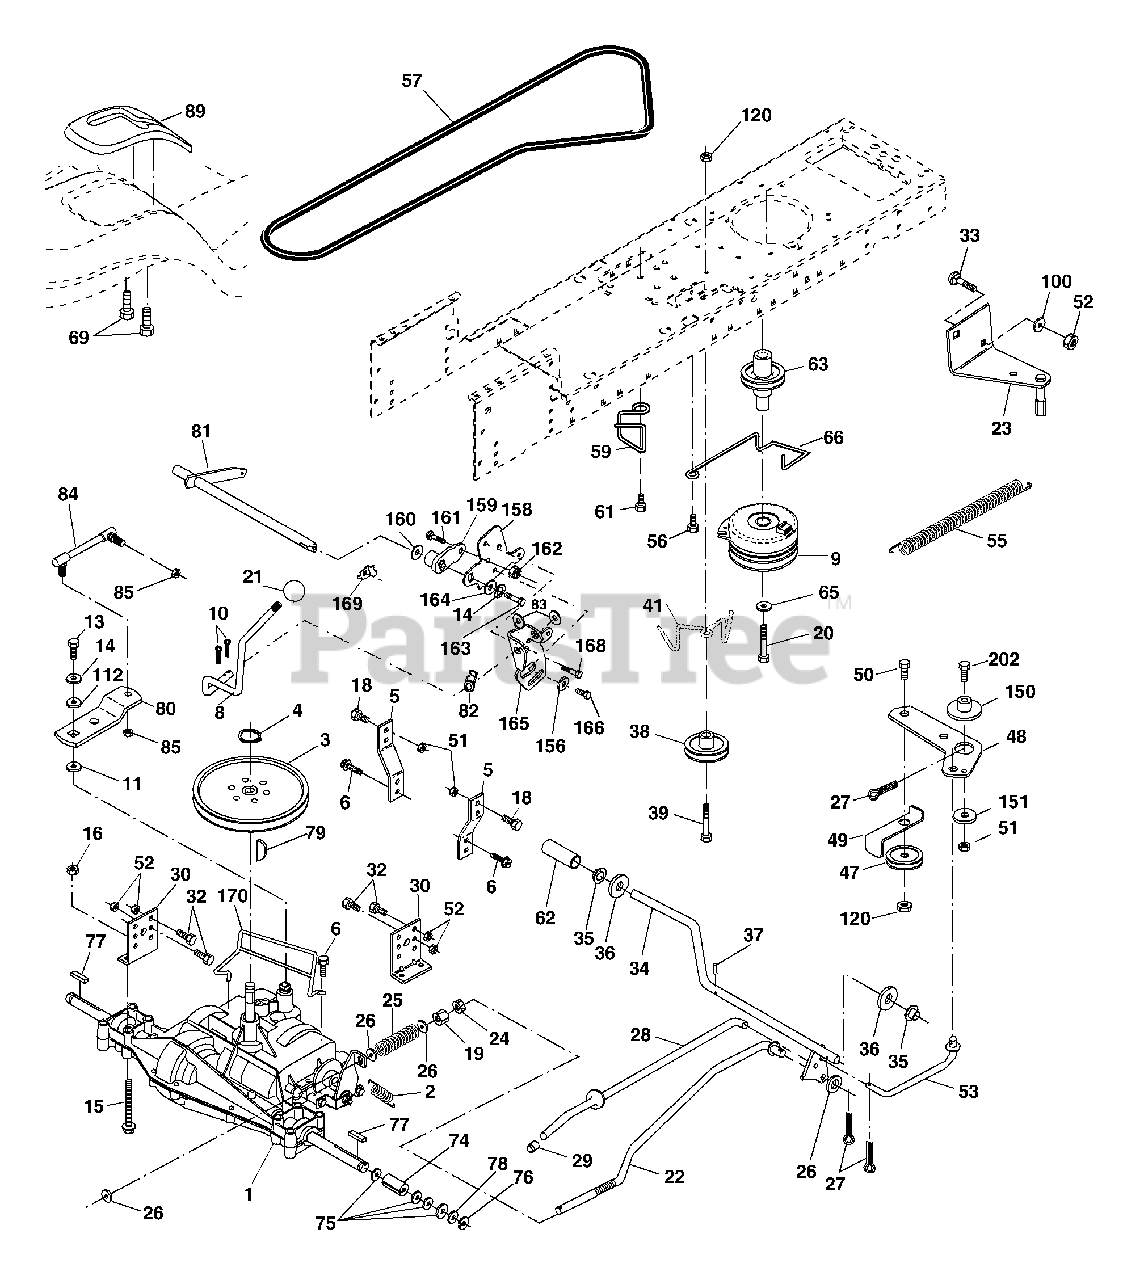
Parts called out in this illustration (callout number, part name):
2	Spring, Return, Brake
3	Pulley, Transaxle
4	Ring, Retainer
5	Strap, Torque
6	Screw 5/16-18 x 3/4
8	Rod Shifter Fender STLT
9	Clutch
10	Pin, Cotter
11	Washer, Shift Plate
13	Bolt 1/4-28 UNF W/Patch Gr. 8
14	Washer Lock Hvy Helical
15	Bolt Hex FLGHD 5/16-18 Gr. 5
16	Nut Lock Hx W/Ins 5/16-18 unc
18	Bolt Fin Hex 3/8-16 unc x 1 Gr. 5
19	Nut
20	Bolt 7/16-20 x 4-1/4 Gr. 5
21	Knob
22	Rod, Brake
23	Bracket Anti-Rotation
24	Nut
25	Spring, Brake Rod
26	Washer
27	Pin
28	Rod, Parking Brake
29	Cap, Parking Brake
30	Bracket, Transaxle
32	Bolt
33	Bolt Rdhd Sqnk 5/16-18 unc x 3/4
34	Shaft Assembly, Foot Pedal
35	Bearing, Nylon
36	Washer
37	Roll Pin
38	Pulley, Composite, Flat
39	Bolt Rdhd 3/8-16 unc x 2-3/4
41	Keeper, Belt, Idler
47	Pulley, Idler, V-Groove, Plastic
48	Bellcrank Clutch Grnd Drv Stl
49	Retainer, Belt
50	Bolt
51	Nut Crown Lock 3/8-16 unc
52	Nut Crown Lock 5/16-18 unc
53	Link, Clutch
55	Spring, Clutch Return
56	Screw 3/8-16 x 1-1/4
57	V-Belt, Ground Drive
59	Keeper, Belt, Center Span
61	Screw 3/8-16 x .875
62	Cover, Pedal
63	Pulley, Engine
65	Washer
66	Keeper, Belt, Engine, Fool Proof
69	Screw Hex Wsh Hi-Lo 1/4-1/2 unc
74	Spacer, Axle
75	Washer 25/32 x 1-1/4 x 16 Ga.
76	E-Ring
77	Key, Square 2.0 x .1845/1865
78	Washer 25/32 x 1-5/8 x 16 Ga.
79	Key Woodruff
80	Arm, Shift
81	Shaft Asm Cross Tapered 20
82	Spring, Torsion
83	Washer 17/32 x 3/4 x 16 Ga.
84	Link Transaxle
85	Nut, Nylock
89	Console, Shift, STLT
96	Retainer Spring 1"
100	Washer 11/32 x 5/8 x 16 Ga.
112	Washer 9/32 x 3/4 x 10 Ga.
113	Strap Torque 90 Degrees
120	Nut Lock Flg. 3/8-16 unc
150	Spacer Retainer
151	Washer 13/32 x 2 x 10 Ga.
156	Washer Srrted 5/16 ID x 1.125
158	Bracket Shift Mount
159	Hub Shift
161	Bolt Rdhd Sqnk 1/4-20 x 3/4 Gr.5
162	Nut Crownlock 1/4-20 unc
163	Bolt Hex Fin 1/4-20Unc x 1 Gr. 5
165	Bracket Pivot Lever
166	Screw 5/16-18 x 5/8 TT Yellow
168	Bolt Shoulder 5/16-18 x .561
169	Plate Fastening Lt
170	Keeper Belt Transaxle Gear
197	Nyliner Snap-In 5/8 ID
198	Washer Nyliner 7/8 ID x .105 Hd
202	Bolt Carr. SH 3/8-16 x 1-3/4 Gr. 5
